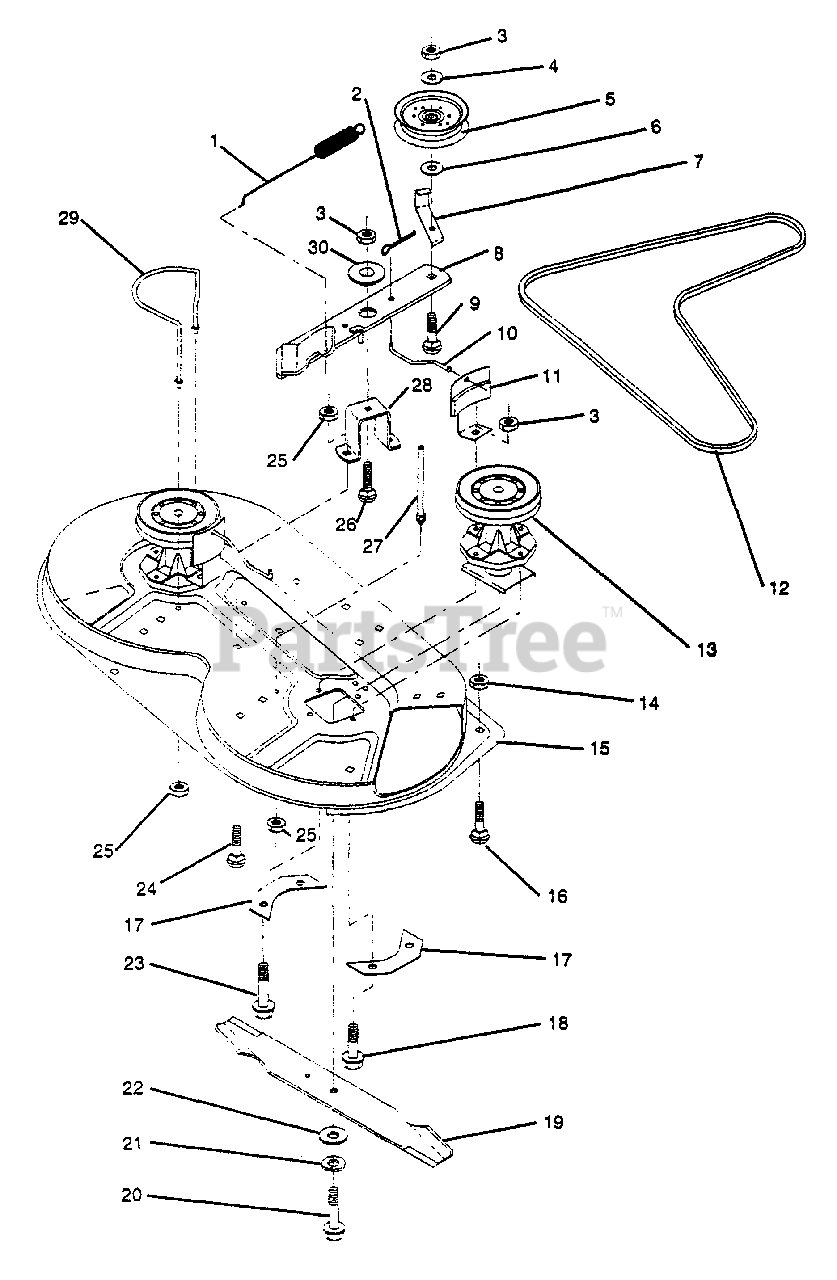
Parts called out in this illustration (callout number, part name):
1	Spring, Mower Clutch
2	Pin, Cotter 3/32 x 3/4
3	Nut, Crownlock 3/8-16 UNC
4	Washer 13/32 x 7/8 x 12 Ga.
5	Idler, Flat
6	Washer 13/32 x 1-3/8 x 3 Ga.
7	Guide, Belt
8	Assembly, Mower Idler Arm
9	Bolt, Carriage 3/8-16 x 2-1/4
10	Rod, Brake
11	Assembly, Brake
13	Assembly, Mandrel
14	Nut, Crownlock 1/4-20
15	Housing, Mower 36"
16	Bolt, Carriage 1/4-20 x 1/2
17	Support, Plate Jackshaft
18	Screw Hex Thdrol. 3/8-16 x 7/8
19	Blade, High Lift
20	Bolt, Fin. Hex 3/8-24 UNF x 1-1/2 Gr. 5
21	Washer, Lock Hvy.3/8
22	Washer 13/32 x 1-1/4 x 12 Ga.
23	Screw Hex Thdrol. 3/8-16 x 1-1/4
24	Bolt, Carriage 5/16-18 UNC x 5/8
25	Nut,Crownlock 5/16-18
26	Bolt, Carriage 3/8-16 UNC x 1 Gr. 5
27	Guide, R.H. Rear Belt
28	Support, Idler Arm
29	Guide, LH. Belt
30	Spacer, Retainer
